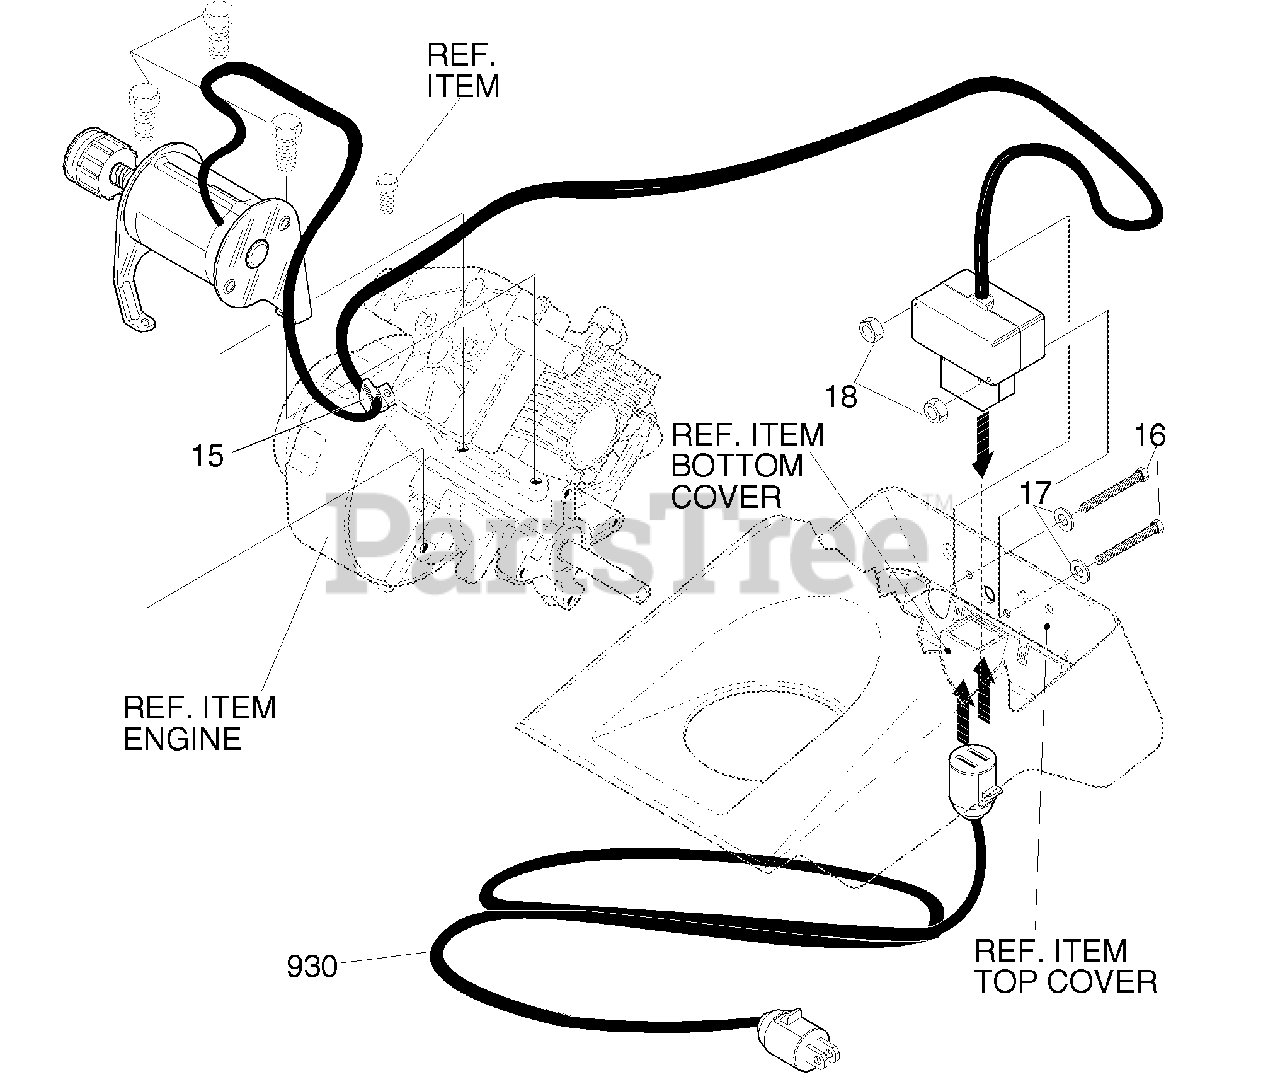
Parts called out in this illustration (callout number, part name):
15	RETAINER, WIRE .31 ID X .62 X .O3
16	SCREW, #8-32 X 3.00 HHC
17	FLATWASHER .188 X .38 X .040
18	NUT, #8-32 HEXKEPS
930	CORD, EXTENSION 10 FEET
